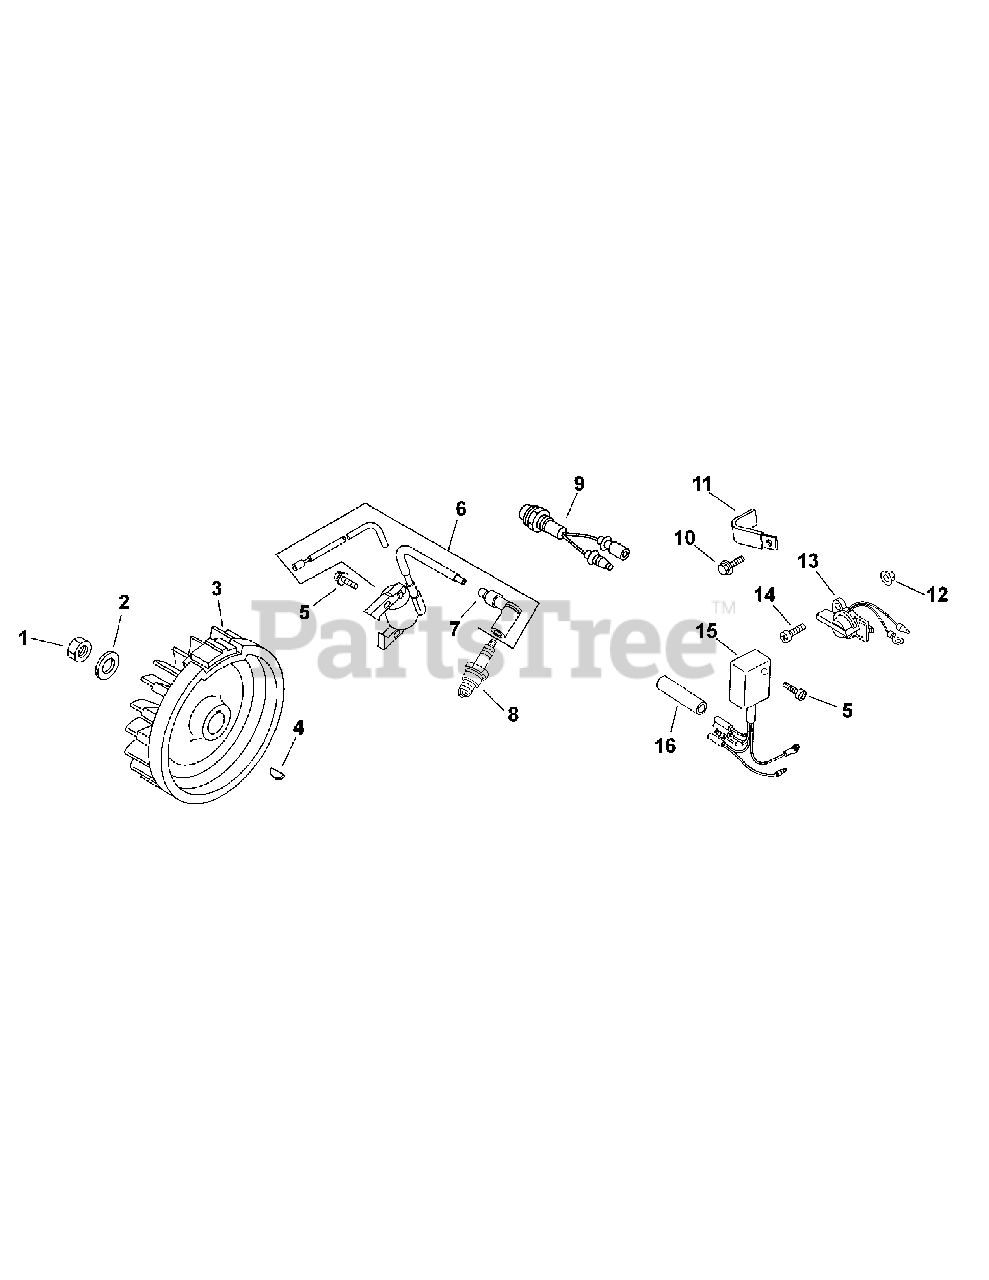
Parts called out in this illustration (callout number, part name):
1	Nut, Flywheel
2	Washer, Flywheel
4	Key, Woodruff
6	Assembly, Ignition Module (Incl. 7)
12	Nut, Stop Switch
14	Screw, Stop Switch
15	Oil Switch Assembly
